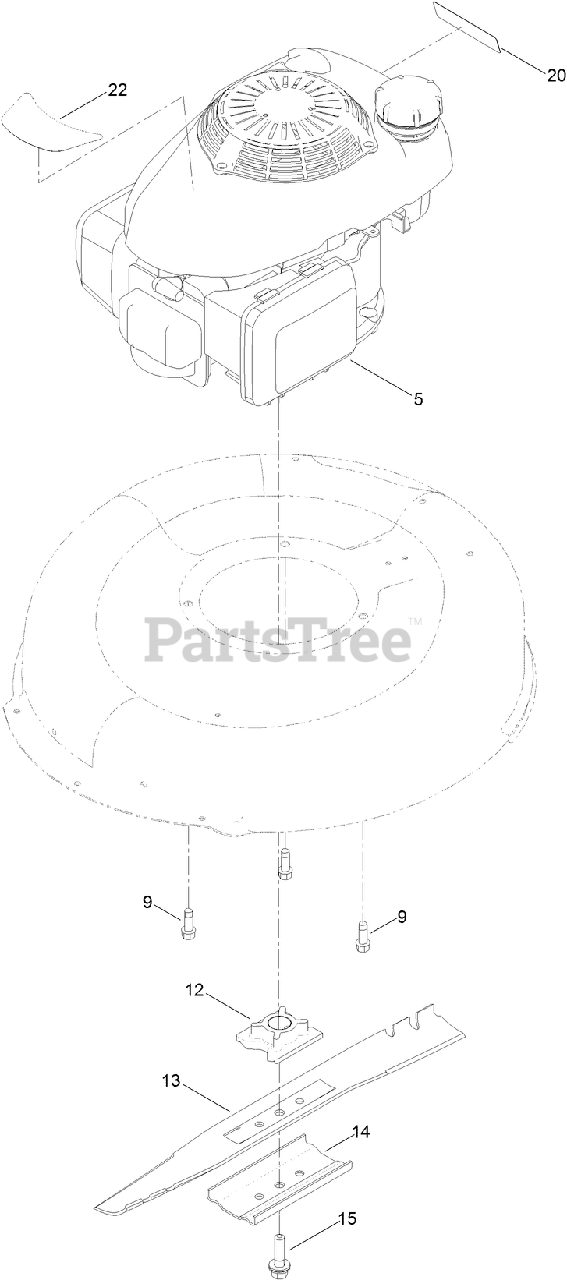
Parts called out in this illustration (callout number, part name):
9	SCREW-TAPTITE
12	RETAINER-BLADE
14	SUPPORT-BLADE
15	BOLT-BLADE
20	DECAL-ARRESTER, SPARK
22	DECAL-SHROUD, HONDA
